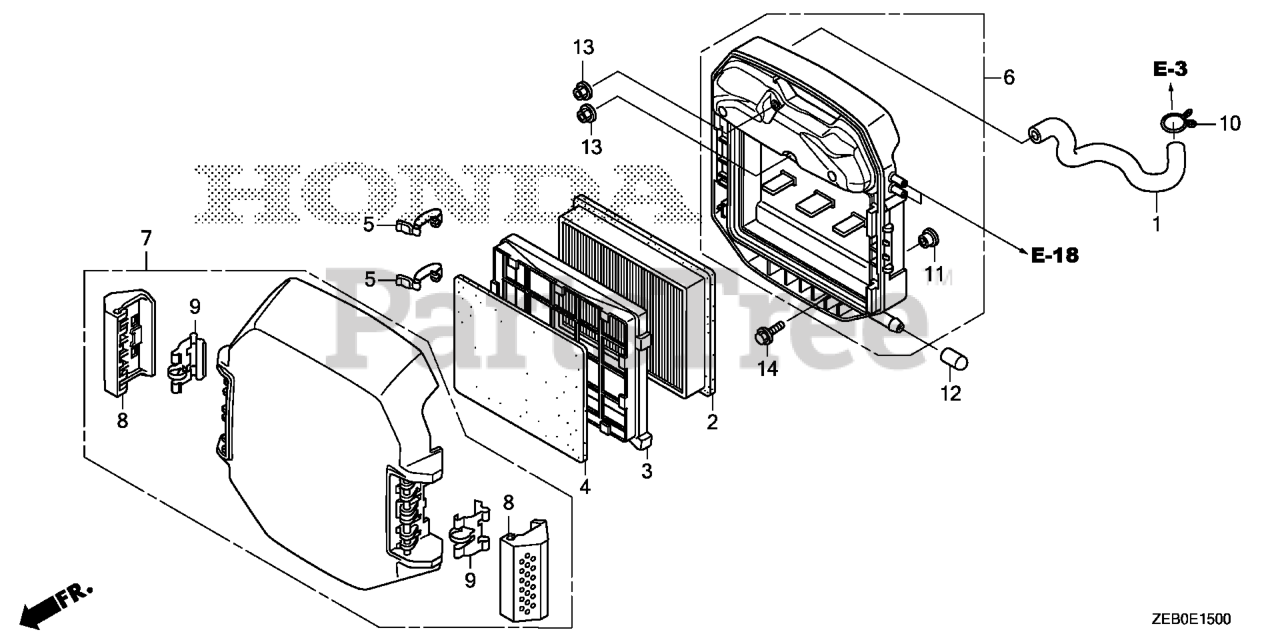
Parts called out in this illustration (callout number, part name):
1	TUBE, BREATHER (NOT AVAILABLE)
2	ELEMENT, AIR CLEANER
3	HOLDER, ELEMENT
4	FILTER (OUTER)
5	CLIP, AIR CLEANER
6	HOUSING, AIR CLEANER (NOT AVAILABLE)
7	COVER, AIR CLEANER (NOT AVAILABLE)
8	KNOB, AIR CLEANER COVER
9	SPRING, AIR CLEANER HOUSING COVER
10	CLIP, BREATHER TUBE
11	COLLAR, FAN COVER
12	CAP, SEALING
13	NUT, FLANGE (6MM)
14	BOLT, FLANGE (6X16) Use from Engine SN 2056820.
